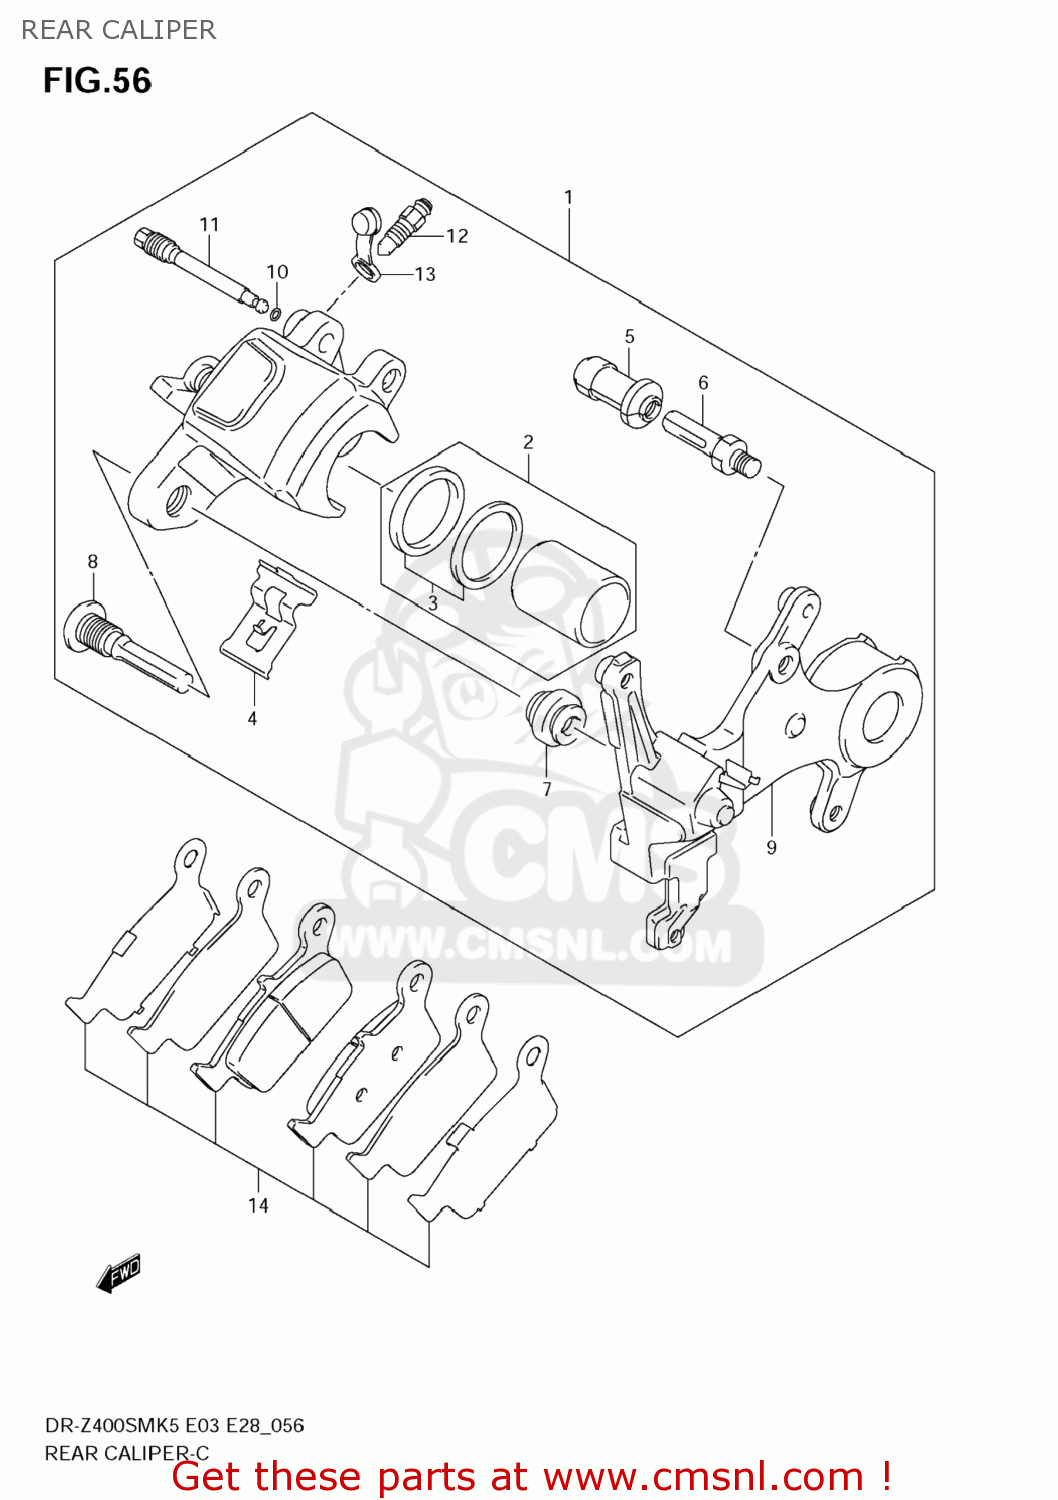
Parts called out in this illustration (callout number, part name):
1	CALIPER ASSY,RR
2	PISTON SET
3	SEAL SET,PISTON
4	SPRING,PAD
5	BOOT
6	BOLT
7	BOOT
8	PIN,BOLT
9	BRACKET
10	RING,STOPPER
11	PIN,HANGER
12	BLEEDER
13	CAP,BLEEDER
14	PAD & RETAINER SET
